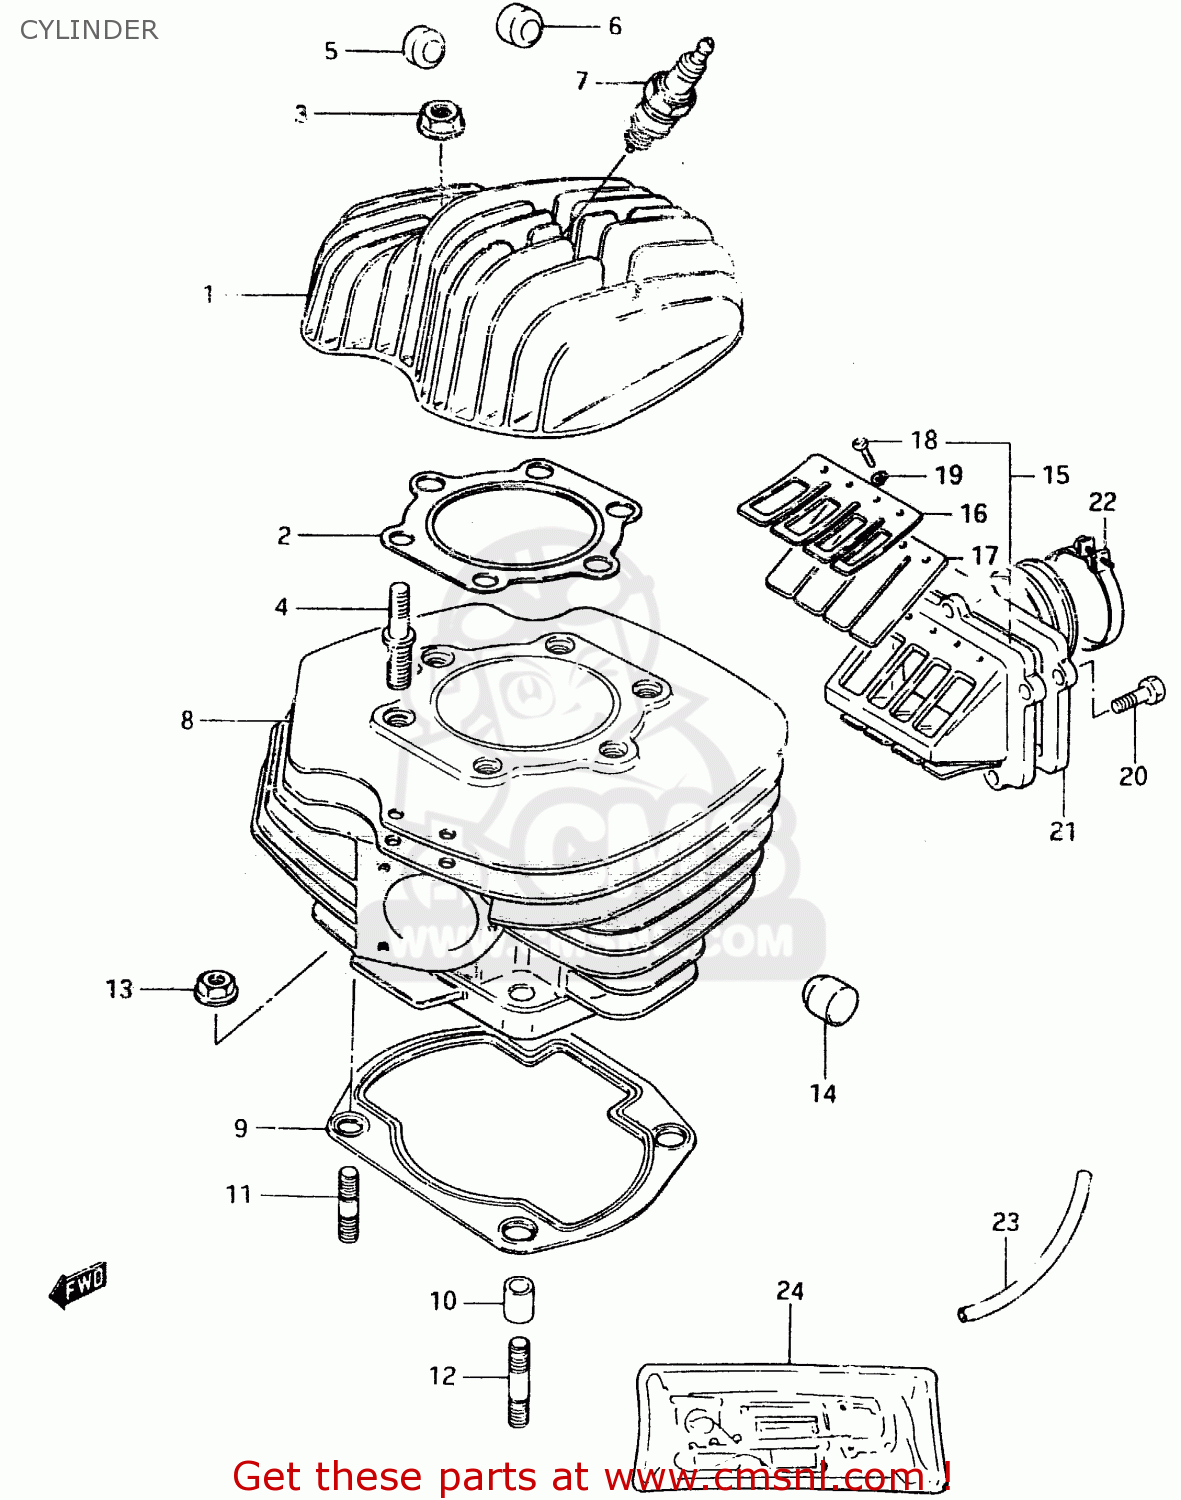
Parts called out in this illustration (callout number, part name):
1	HEAD,CYLINDER
2	GASKET,CYLINDER HEAD (NAS)
3	NUT 8MM
4	STUD
5	PAD,CYLINDER
6	PAD,CYLINDER HEAD
7	SPARK PLUG (NGK,BR8EV)
8	CYLINDER
9	GASKET,CYLINDER (MCA)
10	PIN
11	STUD
12	STUD BOLT
13	NUT
14	PAD,CYLINDER HEAD
15	VALVE ASSEMBLY,REED
16	STOPPER,REED VALVE
17	VALVE,REED
18	SCREW
19	LOCK WASHER
20	BOLT
21	PIPE,INTAKE
22	CLAMP
23	HOSE
24	GASKET
